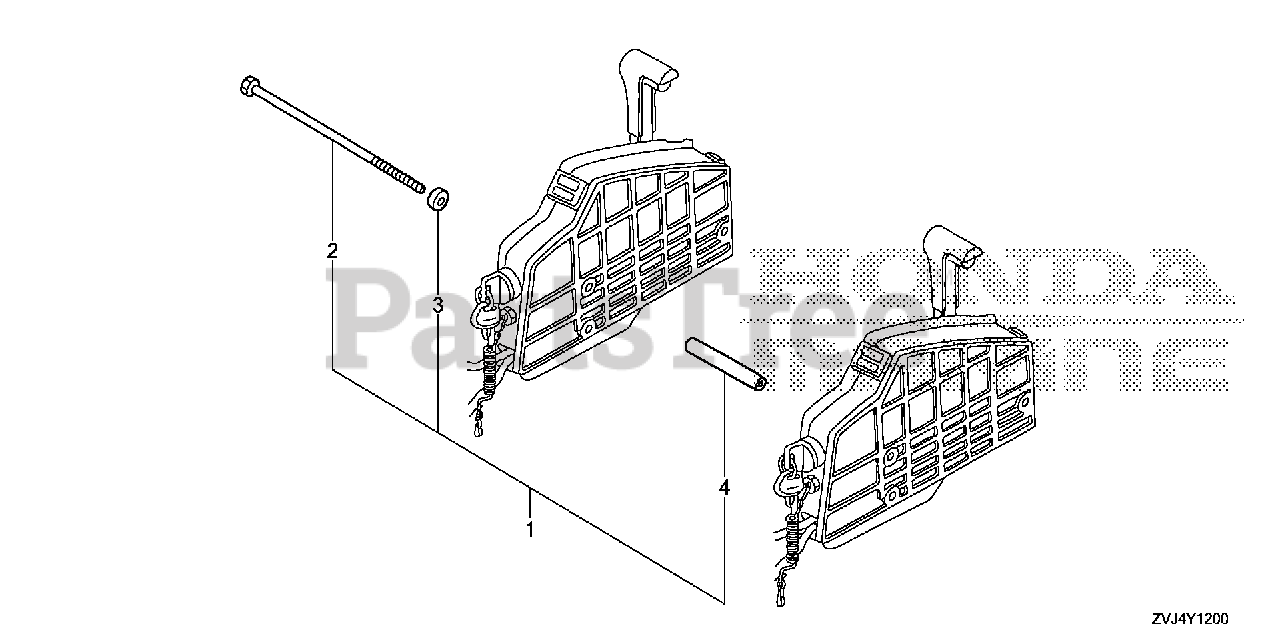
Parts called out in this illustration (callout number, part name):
1	BOLT KIT, SIDE REMOTE CONTROL
2	BOLT, SPECIAL (6X220)
3	COLLAR, DISTANCE (A)
4	COLLAR, DISTANCE (B)
